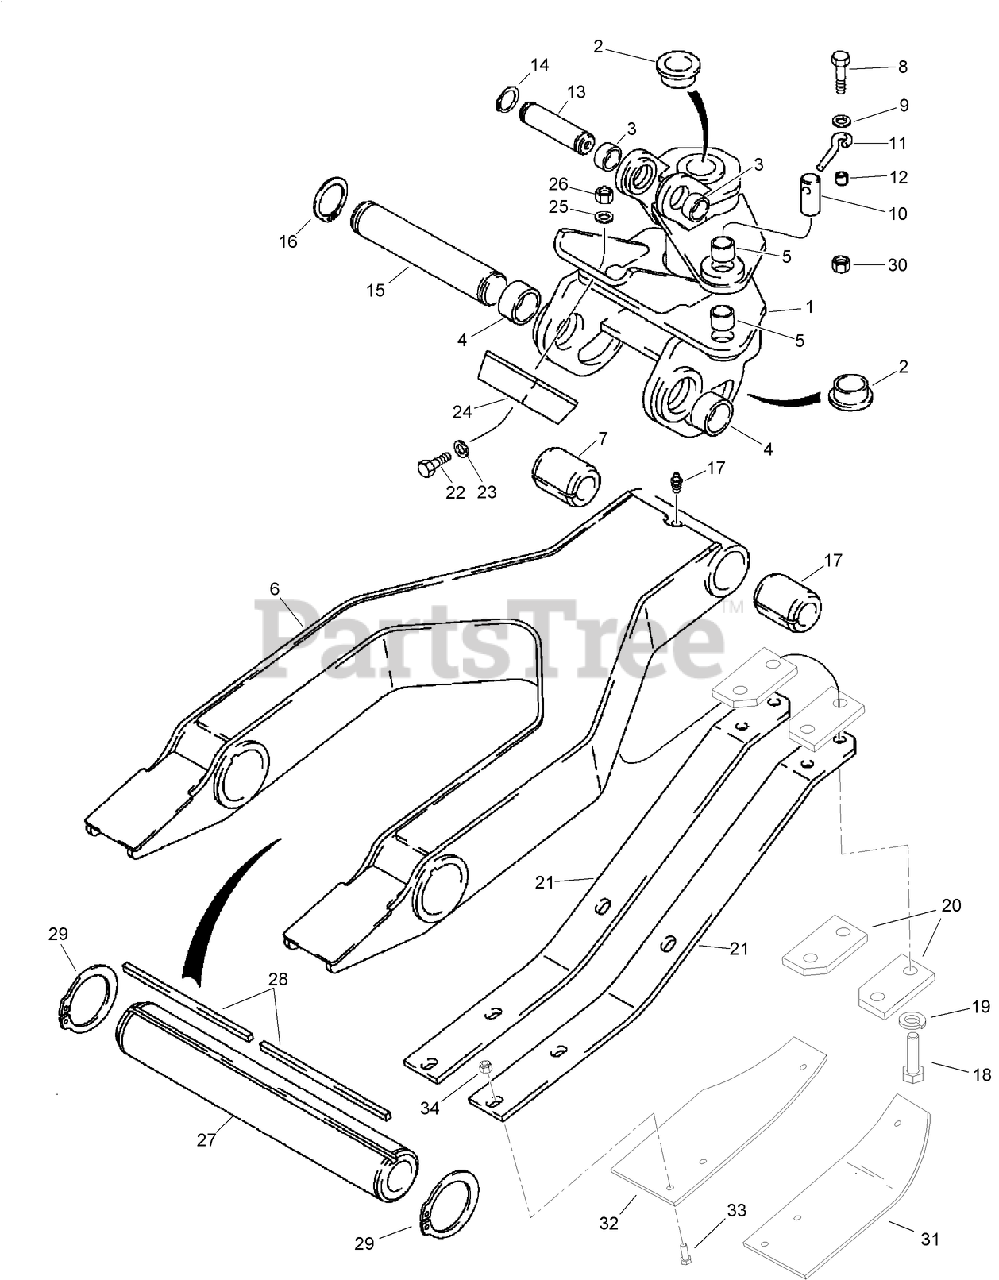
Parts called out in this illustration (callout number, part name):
1	TOWER-plow swing
2	BUSHING-PIVOT, BUCKET
3	BUSHING-plow swing tower, upper pivot
4	BUSHING-25 mm (1 inch) long, plow swing tower, lower pivot
5	BUSHING-arm, 25 mm (1 inch) ID, plow swing tower, swing cylinder pivot
6	ARM-plow lift
7	BUSHING-ARM, PLOW
8	BOLT-hex, 5/16 NC x 1-3/4 inch
9	WASHER-FLAT
10	PIN-pivot
11	PIN-RETAINER
12	SPACER-13 mm (1/2 inch) long
13	PIN-pivot, swing tower, small
14	RING-RETAINING
15	PIN-pivot, 10-7/8 inch long, swing tower, large
16	RING-RETAINING, EXTERNAL
17	FITTING-grease, 45 degree, 1/8 PT self-tap x 25/32 inch
18	BOLT-Hex Hd 1/2 x 1-3/4 GR5 ZND
19	WASHER-Spring Lock Reg 1/2 ZND
20	PLATE-skid shoe support
21	SHOE-skid, plow
22	BOLT
23	WASHER-FLAT
24	BUMPER
25	WASHER-FLAT
26	NUT-HEX
27	PIN-pivot, rear
28	KEY-square, 9.5 x 250 mm, plow pivot pin, rear
29	RING-external retaining, No. 300, rear plow pivot pin retaining
30	NUT-HEX
31	PLATE-skid shoe, right-hand
32	PLATE-skid shoe, left-hand
33	BOLT-hex socket head, 3/8 NF x 1 inch, grade 8
34	NUT-hex jam, self-locking, 3/8 inch NF
